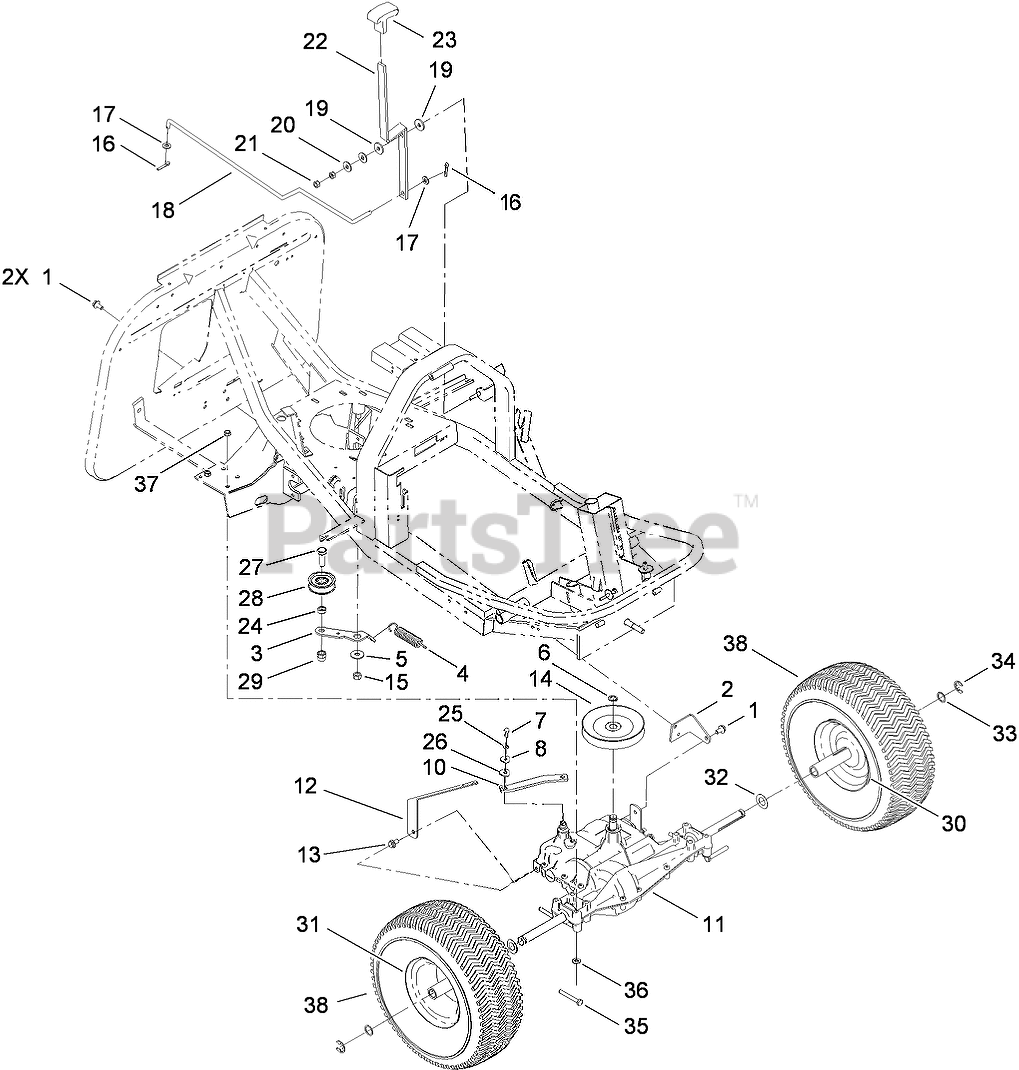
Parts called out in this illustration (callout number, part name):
1	SCREW-HHF TAP
2	Bracket
3	Bracket-Idler
4	Spring-Extension
5	Washer-Flat
6	Ring-External
7	SCREW-HH
8	Washer-Flat
10	Bracket
11	DIFFERENTIAL-GEAR
12	PLATE-SWITCH, TRANSMISSION
13	SCREW-HHF TAP
14	Pulley
15	NUT-LOCK, NI
16	PIN-COTTER
17	WASHER-PLAIN
18	LINK-TRANSMISSION, DANA
19	Washer
20	Washer-Flat
21	NUT-HEX
22	Lever-Clutch
23	Handle
24	Spacer
25	Washer-Lock/Sp
26	Washer-Flat
27	SCREW-HH
28	PULLEY
29	NUT-LOCK
30	WHEEL-REAR LEFT
31	WHEEL-REAR RIGHT
32	SPACER-INNER
33	SPACER-OUTER
34	RING-RETAINING, EXT
35	SCREW-HH
36	WASHER-PLAIN
37	NUT-LOCK
